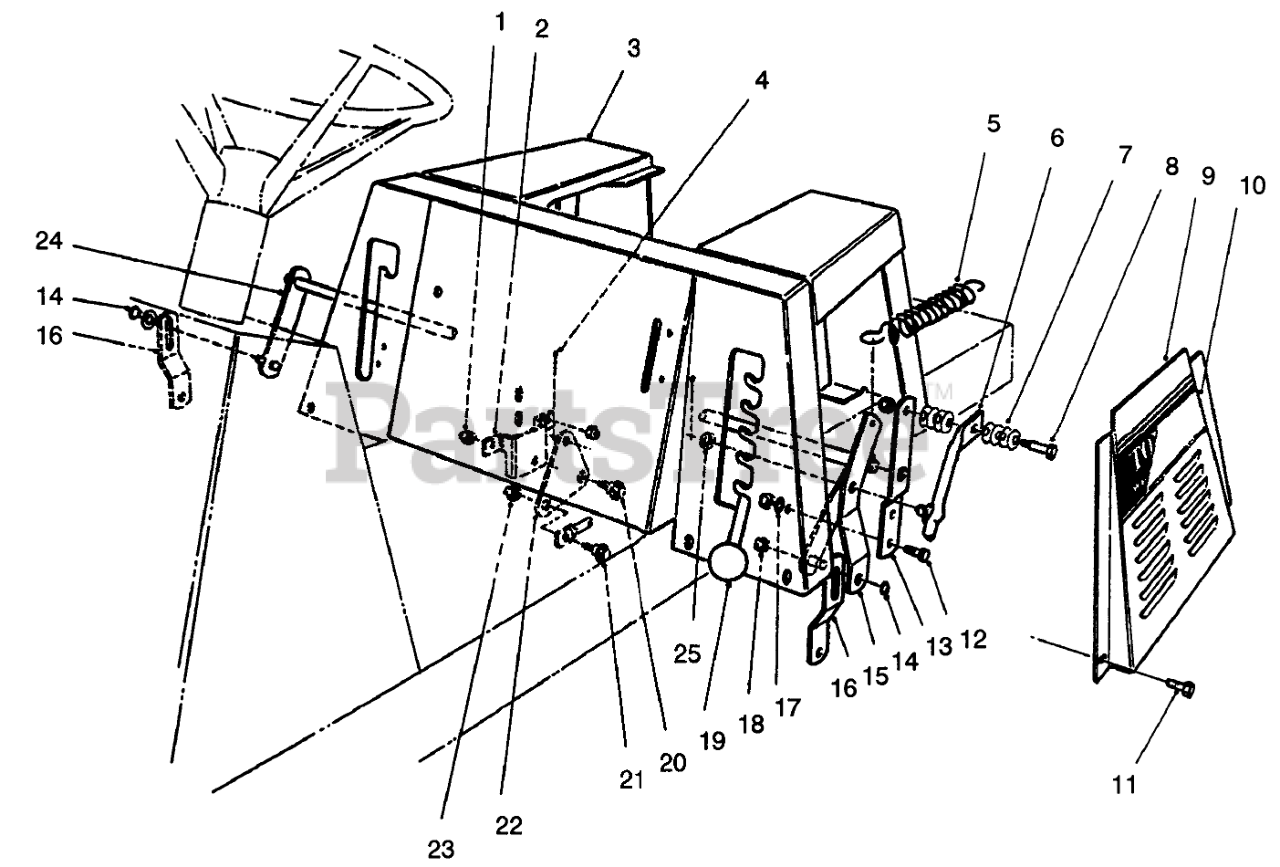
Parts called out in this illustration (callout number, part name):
1	NUT-LOCK, NI
2	BRKT-B.CRANK MTG
3	SEAT BODY WA R
4	PIN-COTTER
5	SPRING-EXTENSION
6	HOC LEVER WA B
7	WASHER-BELLEVILLE
8	BOLT-SHOULDER
9	L/H SEAT BASE PANELR
10	DECAL - LH TORO 10-32
11	SCREW-HH
12	SCREW-HH
13	Bracket
14	RING-RETAINING
15	Bracket-H.O.C., Engage
16	Link-Deck Suspension
17	WASHER-PLAIN
18	NUT-LOCK, NI
20	SCREW-SHOULDER
21	SCREW-SHOULDER
22	BELLCRANK
23	NUT-HEX
24	Arm
25	WASHER-FLAT
